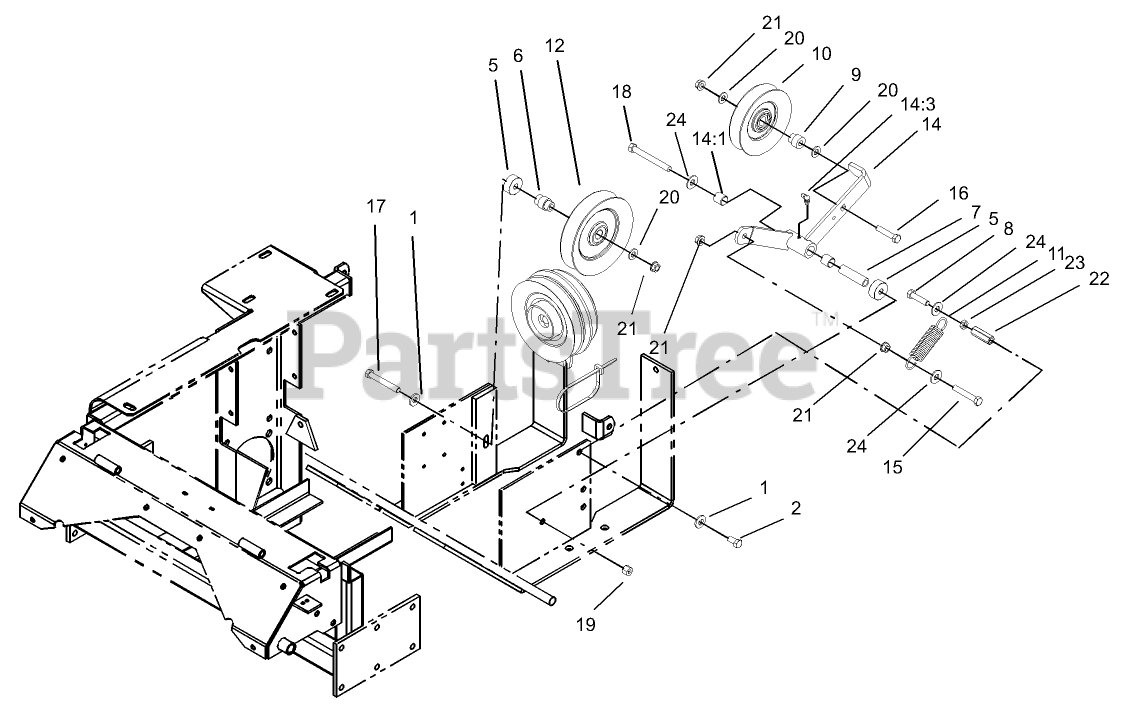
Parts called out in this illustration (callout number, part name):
1	WASHER-BELLEVILLE
2	SCREW-HH
5	Spacer-Idler
6	Bushing-Idler
7	BUSHING-PIVOT, IDLER
8	SCREW-HH
9	BUSHING-IDLER
10	Idler
11	SPRING-EXTENSION
12	PULLEY-IDLER
14	IDLER ARM ASM
14:1	SLEEVE-BEARING
14:3	FITTING-GREASE, 90 DEG
15	SCREW-HH
16	SCREW-HH
17	SCREW-HH
18	SCREW-HH
19	NUT-LOCK, NI
20	WASHER-FLAT
21	NUT-HHF, WHIZ
22	Nut-Coupling
23	NUT-JAM
24	WASHER-FLAT
